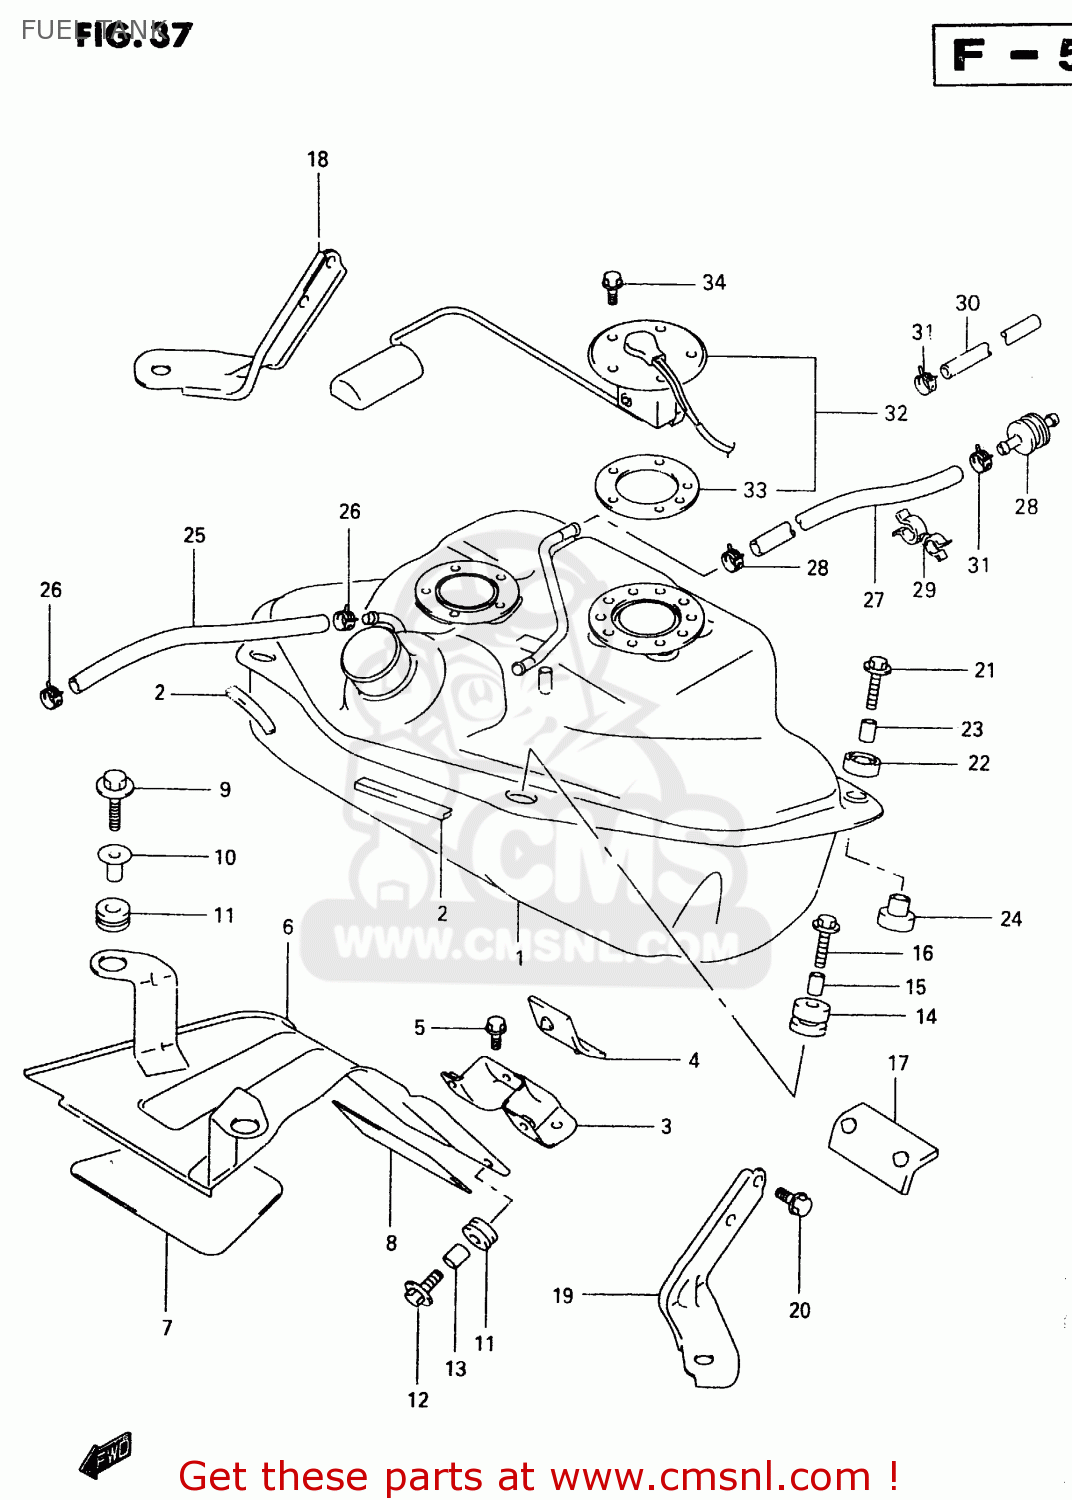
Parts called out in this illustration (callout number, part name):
1	TANK,FUEL
2	MOLDING
3	BRACKET,FUEL TANK FR
4	CUSHION,FUEL TANK FR
5	BOLT
6	COVER COMP,FUEL TANK,FRONT
7	SHIELD,FR COVER UPR
8	SHIELD,FR COVER LWR
9	BOLT(6X30)
10	WASHER
11	CUSHION
12	BOLT
13	SPACER(6.1X8X9.5)
14	CUSHION,FUEL TANK SIDE
15	SPACER(6.5X9X12.5)
16	BOLT(6X25)
17	CUSHION,FUEL TANK RR CTR
18	BRACKET,FUEL TANK RR,R
19	BRACKET,FUEL TANK RR,L
20	BOLT
21	BOLT(6X30)
22	CUSHION
23	SPACER(6.5X9X18)
24	CUSHION
25	HOSE(11X16X600)
26	CLIP
27	HOSE(5.4X11.4X600)
28	VALVE,2WAY CHECK
29	CLAMP
30	HOSE(5.4X11.4X600)
31	CLIP
32	GAUGE ASSY,FUEL LEVEL
33	GASKET,FUEL LEVEL GAUGE (NAS)
34	BOLT 5X10
